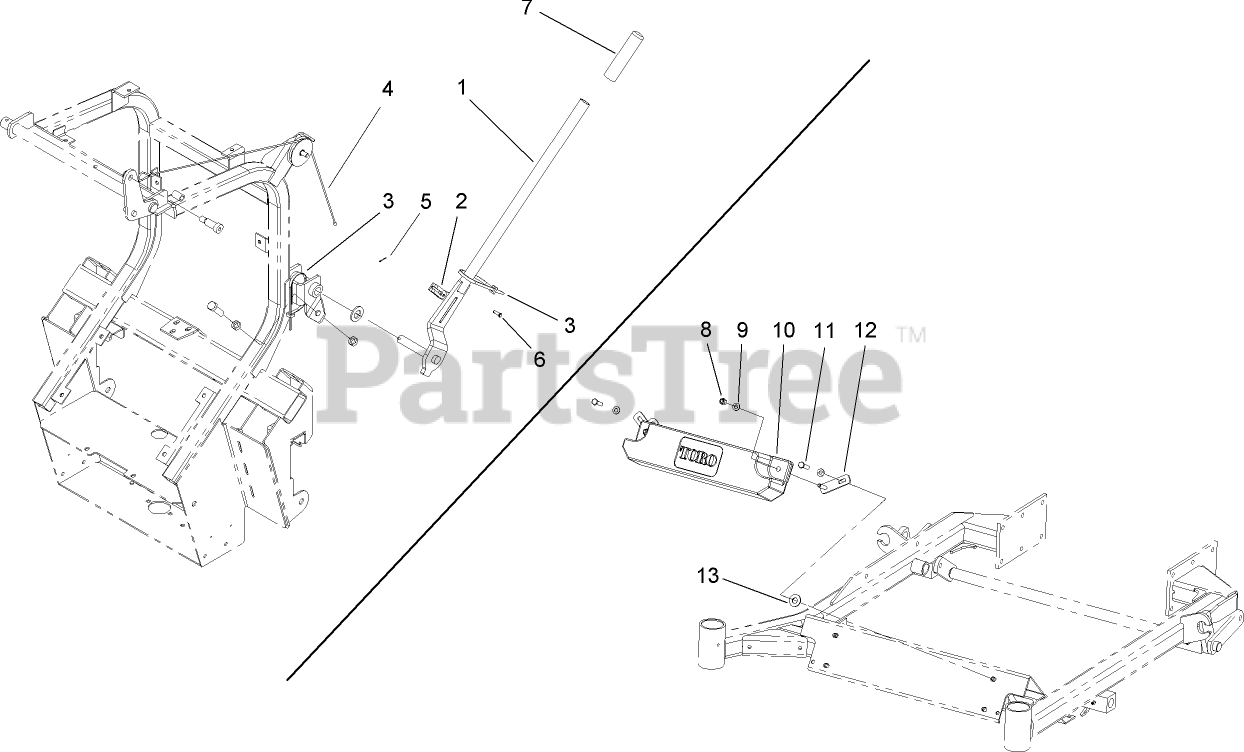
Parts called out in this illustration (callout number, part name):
1	Dump Arm ASM
2	CLEVIS-SHORT
3	TIE-CABLE
5	PIN-COTTER
6	PIN-CLEVIS
7	GRIP-FOAM
8	NUT-LOCK, NI
9	WASHER-PLAIN
10	WEIGHT-REAR
11	SCREW-HH
12	ARM WEIGHT MOUNT ASM
13	WASHER
